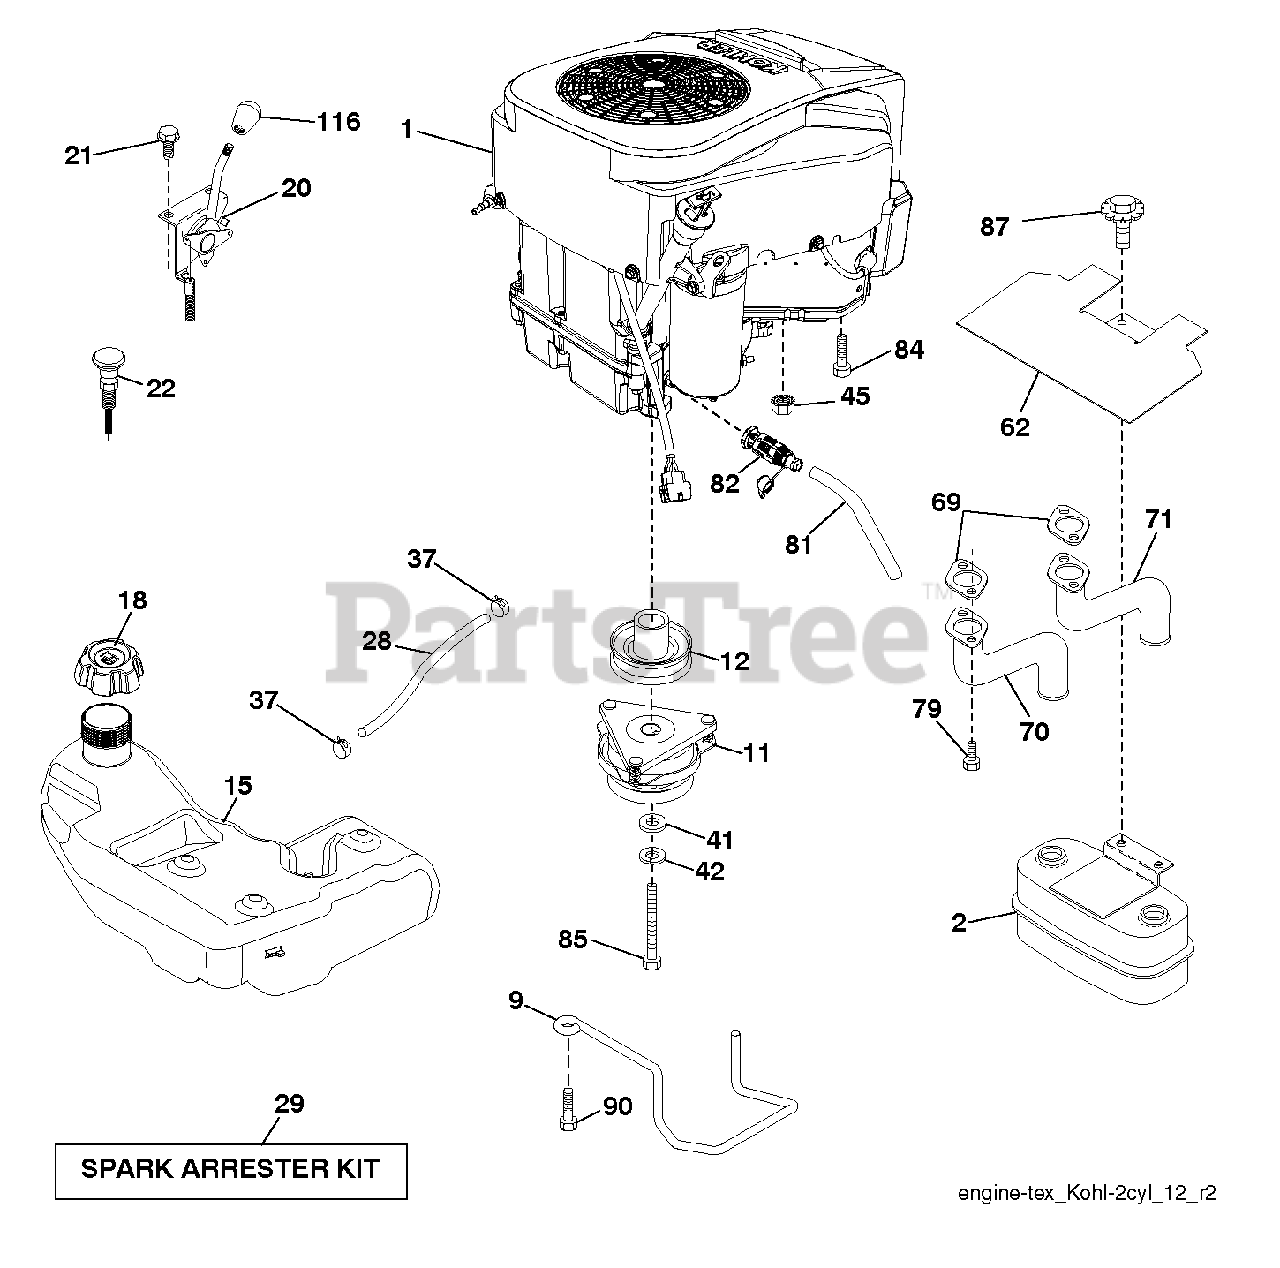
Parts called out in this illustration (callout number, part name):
2	MUFFLER.TWIN.CYL.LOW.TONE
9	KEEPER BELT ENGINE
11	CLUTCH.ELECTRIC.LT.48"*
12	PULLEY.ENGINE.TUFFTORQ
15	TANK.ASSY.3.GAL.EPA
18	CAP ASM.FL.RTCHT.3"GRY.E10
20	CONTROL.THROTTLE.PRO.KOHLER
21	SCREW.#10 X 0.750.BOS (2 2)
22	CONTROL CHOKE
29	KIT.SPARK ARRESTOR(392390 B&S)
37	HOSE CLAMP
42	LOCKWASHER
45	NUT
62	SHIELD.HEAT.MUFFLER
70	PIPE.EXHAUST.LH.CV18/20
71	PIPE.EXHAUST.RH.CV18/20
79	SCREW.SOCKET HD.5/16-1
81	TUBE, DRAIN OIL ASM.
82	VALUE.OIL.DRAIN
84	SCREW 3/8-16X1
85	BOLT HEX 7/16-20X4-1/4"
87	BOLT.5/16-18UNCX1.W/SEMS.BLK
90	SCREW 3/8-16X1
116	KNOB - SHIFT
